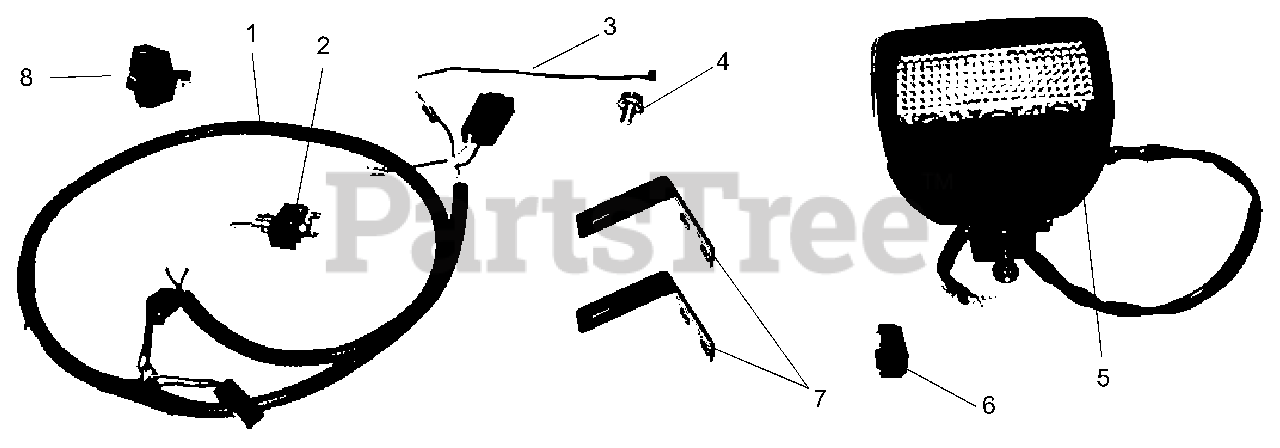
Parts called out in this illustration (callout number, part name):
1	HARNESS, HEADLIGHT KIT
2	SWITCH, ON/OFF
3	CABLE TIE LG 5-1/2
4	@SCR-TAP .38-16X.50 HWH TR YWZ
5	HEADLIGHT
6	Connector Shell
7	BRACKET, HEADLIGHT MTG
8	SWITCH, 2 POLE/ROCKER
